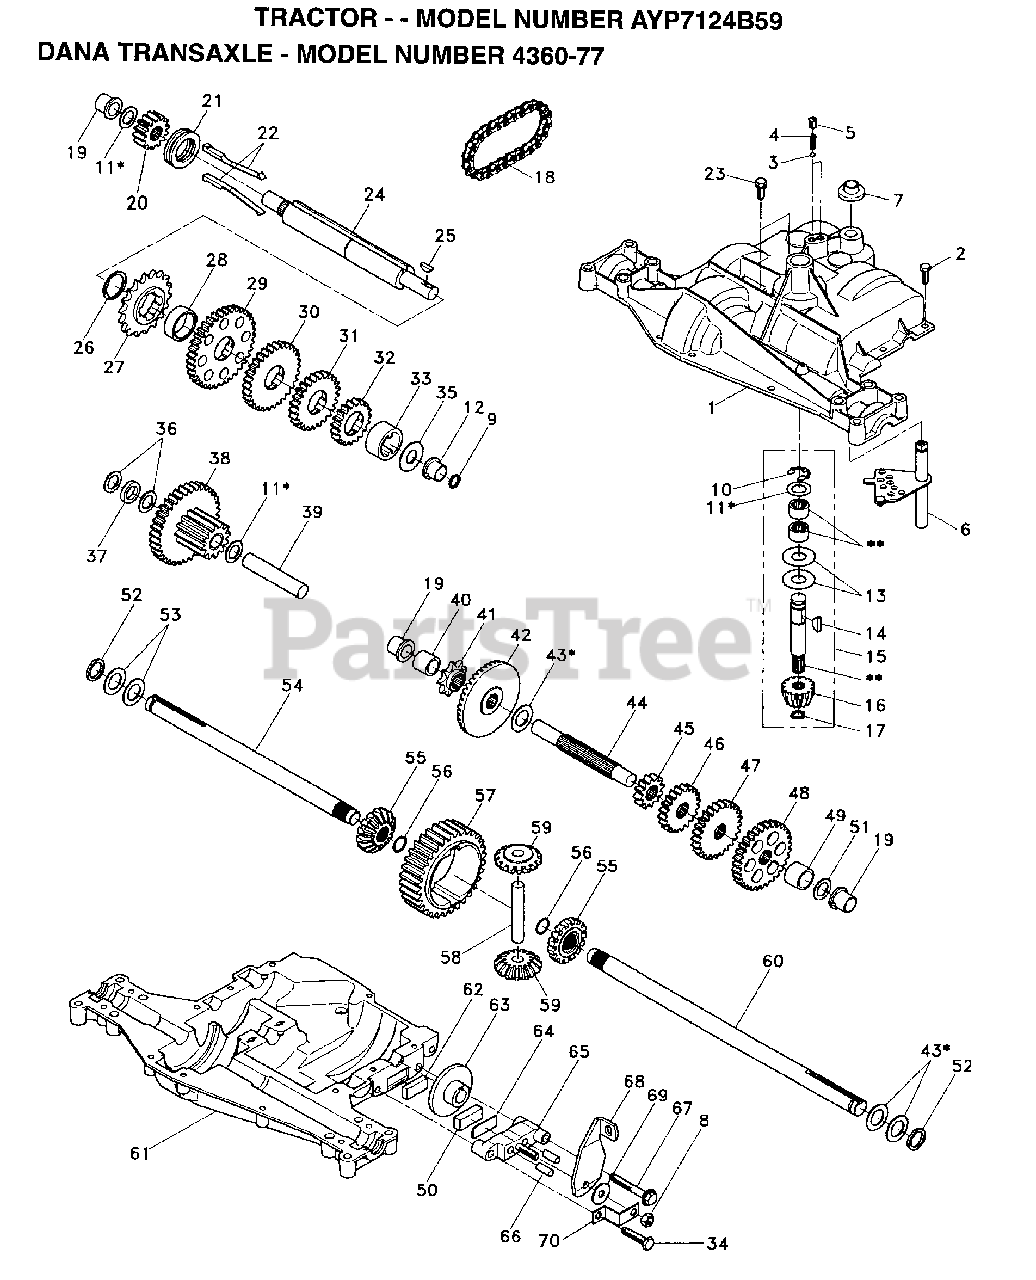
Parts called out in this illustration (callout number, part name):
1	HOUSING, UPPER
3	BALL, DETENT
4	SPRING, DETENT
5	SCREW, SET
6	SHIFTER ASSEMBLY
7	BOOT, SHIFTER
10	RING, RETAINING
11	ASSY, KIT, SHIM .625 SHAFT
12	BEARING, FLANGE
13	WASHER, PLAIN .632 X 1.38 X .046
14	KEY, WOODRUFF, #9
15	ASSEMBLY, KIT, INPUT SHAFT
16	PINION, BEVEL, 14 TEETH
17	RING, RETAINING
18	CHAIN, 24 PITCHES
19	BEARING, FLANGE
20	GEAR, SPUR, 14 TEETH
21	COLLAR, CLUTCH
22	ASSEMBLY, KIT, CLUTCH KEYS
23	SCREW TAPPING WITH SEALER
24	SHAFT, INTERMEDIATE
25	KEY, WOODRUFF, #61
26	RING, RETAINING
27	SPROCKET, 18 TEETH
29	GEAR, SPUR, 37 TEETH
30	GEAR, SPUR, 30 TEETH
31	GEAR, SPUR, 25 TEETH
32	SPACER 1.133 X 1.50 X .750
33	GEAR, SPUR, 22 TEETH
34	SCREW TAPPING
35	WASHER, PLAIN .640 X 1.37 X .061
36	WASHER, PLAIN .632 X 1.00 X .026
37	SPACER .630 X 1.00 X .169
38	ASSY GEAR COMB 12&35 TEETH
39	SHAFT, IDLER
40	SPACER .635 X .875 X .755
41	SPROCKET, 9 TEETH
42	GEAR, BEVEL, 42 TEETH
43	ASSY, KIT, SHIM .750 SHAFT
44	SHAFT, DRIVE
45	GEAR SPUR, 12 TEETH
46	GEAR, SPUR, 20 TEETH
47	GEAR, SPUR, 25 TEETH
48	GEAR, SPUR, 31 TEETH
49	SPACER .781 X 1.00 X .750
50	PUCK, FRICTION
51	WASHER, PLAIN .632 X 1.00 X .060
52	WASHER, NEOPRENE
53	WASHER, PLAIN .758 X 1.25 X .031
54	AXLE LEFT HAND
55	GEAR, MITER, 15 TEETH
56	RING, RETAINING
57	GEAR, SPUR, 32 TEETH
58	LOCKNUT 5/16-24
58	SHAFT, CROSS
59	GEAR, MITER, 15 TEETH
60	AXLE, R.H.
61	HOUSING, LOWER
62	PUCK, FRICTION
63	DISC, BRAKE
65	JAW, BRAKE
66	PIN, DOWEL
67	SCREW, SELF-TAPPING
68	LEVER ACTUATING
69	WASHER, PLAIN .321 X 1.00 X .055
70	BRACKET, ANTI-ROTATION
